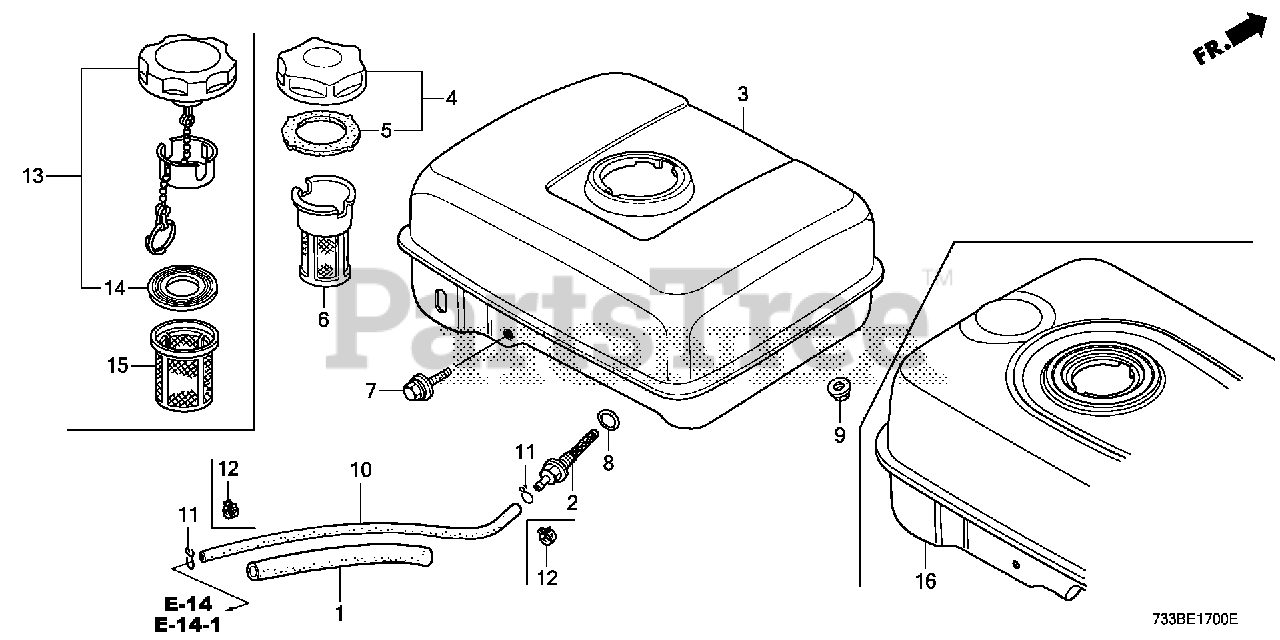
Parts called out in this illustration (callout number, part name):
1	RUBBER, SUPPORTER (107MM)
2	JOINT, FUEL TANK
3	TANK, FUEL *R280* (POWER RED)
7	BOLT, FLANGE (6X29)
8	O-RING (14MM) (ARAI) Use up to Engine SN 2949254.
8	O-RING (14MM) (NOK)
9	NUT, FLANGE (6MM)
10	TUBE, FUEL (4.5X145) (FKM)
12	CLIP, TUBE (D8)
13	CAP, FUEL FILLER
14	GASKET, FUEL FILLER CAP
14	GASKET, FUEL FILLER CAP (39X62X3) (TOUYOUSYA)
15	FILTER, FUEL
16	TANK, FUEL *R280* (POWER RED)
